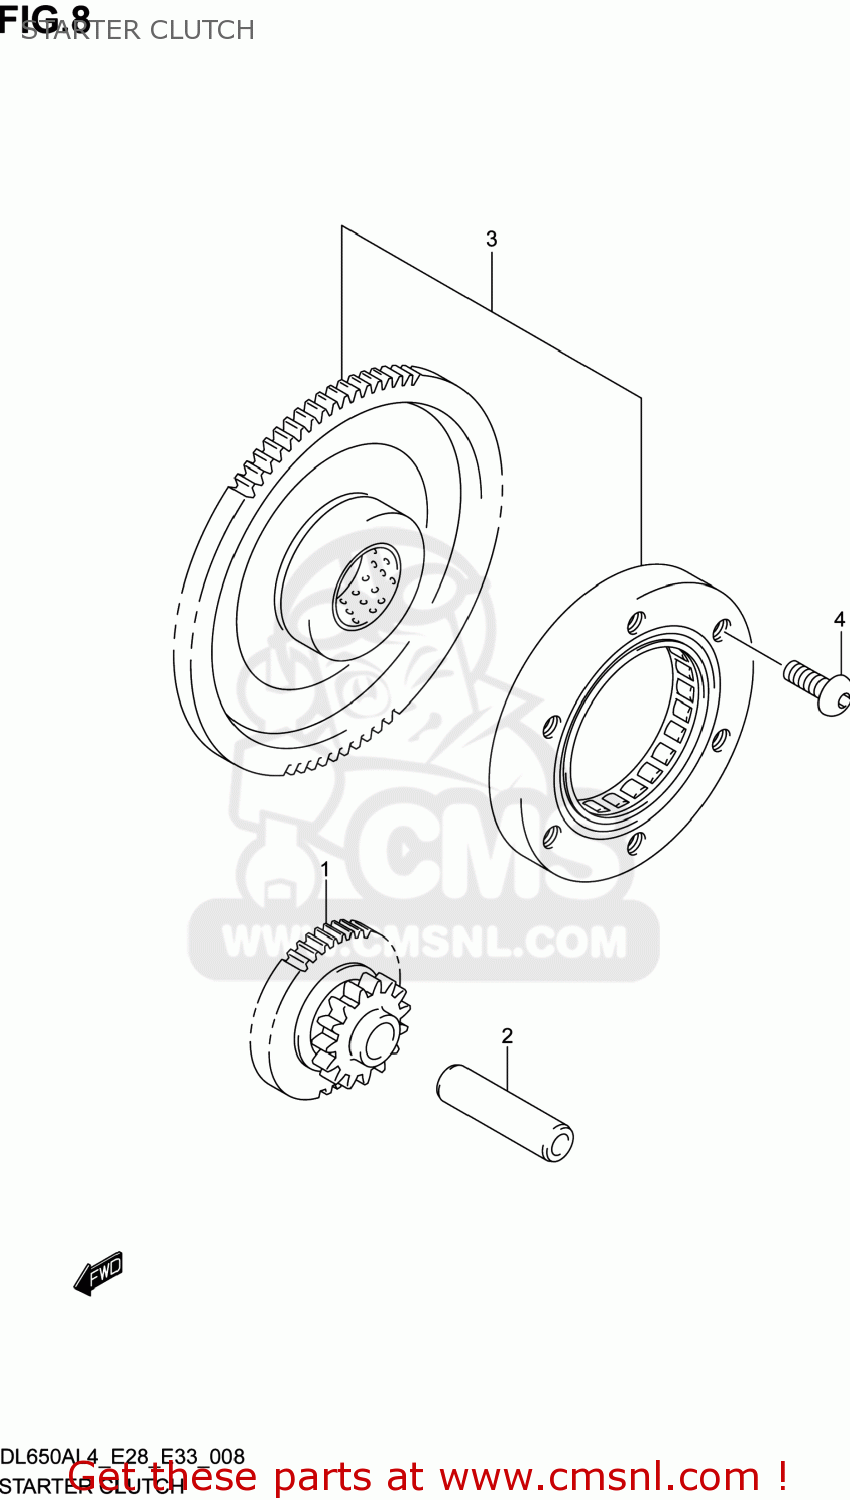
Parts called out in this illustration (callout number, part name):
1	GEAR,STARTER IDLE
2	PIN(8X12X45.5)
3	CLUTCH SET,STARTER
4	SCREW(8X16)
